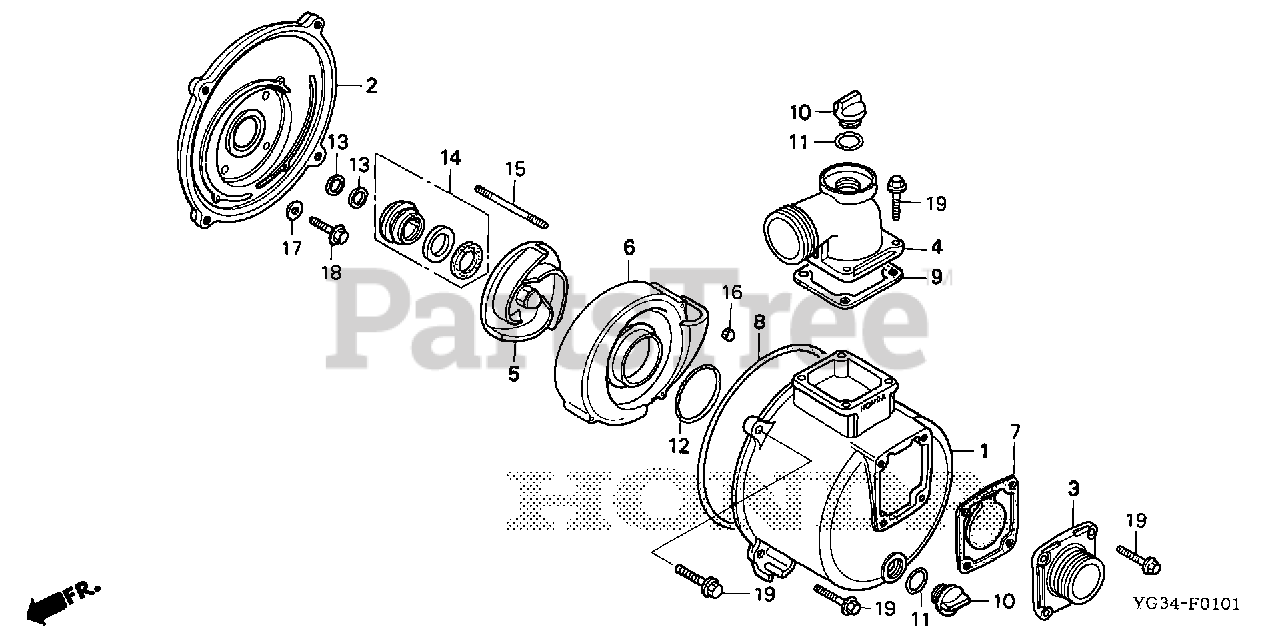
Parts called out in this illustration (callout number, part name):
2	COVER, CASING
3	INLET (NPTF)
3	INLET (FOR U.S.A.) (NPTF)
4	OUTLET (NPTF)
4	OUTLET (FOR U.S.A.) (NPTF)
6	CASE, VOLUTE
7	VALVE, IN.
8	RING, CASING SEAL
8	O-RING (232X3.5)
9	GASKET, OUTLET
10	CAP, FILLER
11	O-RING (23.7X3.5)
12	O-RING (71X5.7)
13	SHIM, ADJUSTER
14	SEAL ASSY., MECHANICAL WATER
15	BOLT, STUD (6X50)
16	NUT, CAP (6MM)
17	WASHER, SEALING (8MM)
18	BOLT, FLANGE (8X28)
19	BOLT, FLANGE (10X32)
